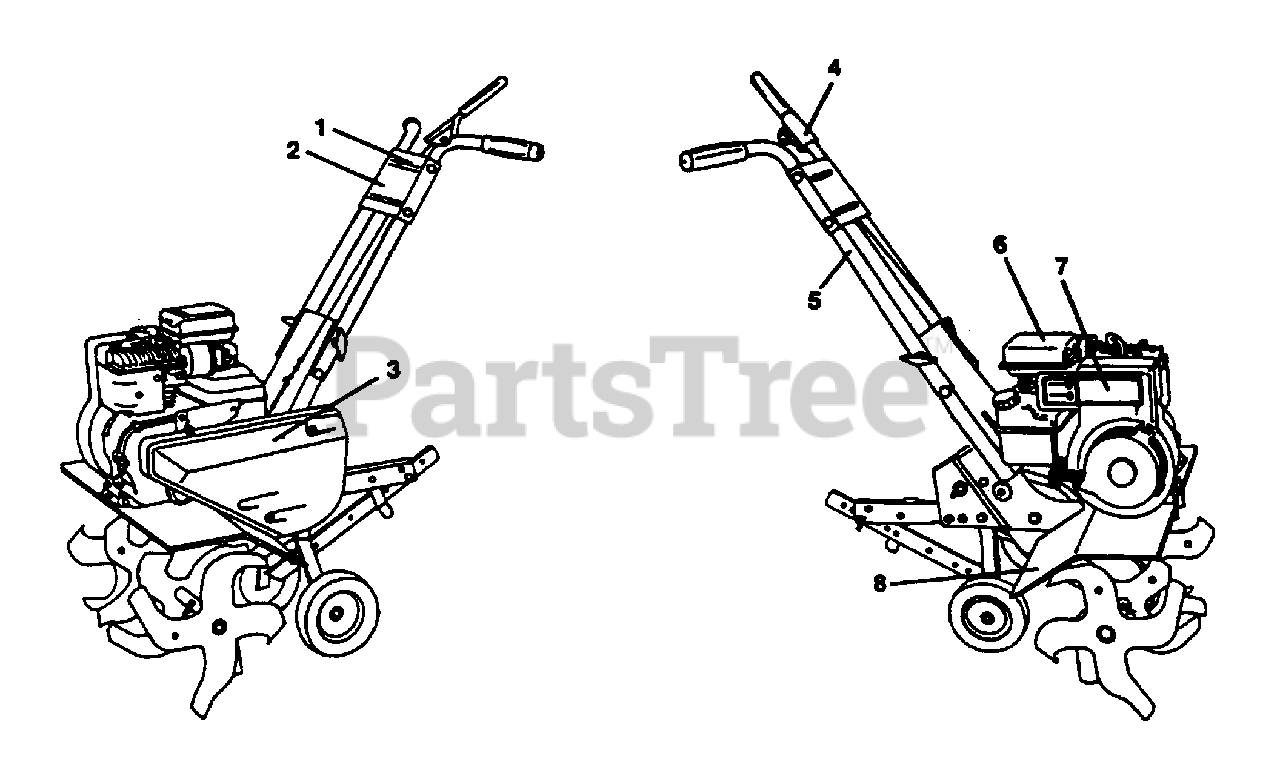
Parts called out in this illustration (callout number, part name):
1	Decal, Logo
2	Decal, HP (AYP part number)
3	Decal, Logo (AYP part number)
4	Decal, Tine Control (AYP part number)
5	Decal, Hand Placement (AYP part number)
6	Decal, Caution (AYP part number)
7	Decal, Briggs & Stratton (AYP part number)
8	Decal, Warning, Rotating Tines (AYP part number)
